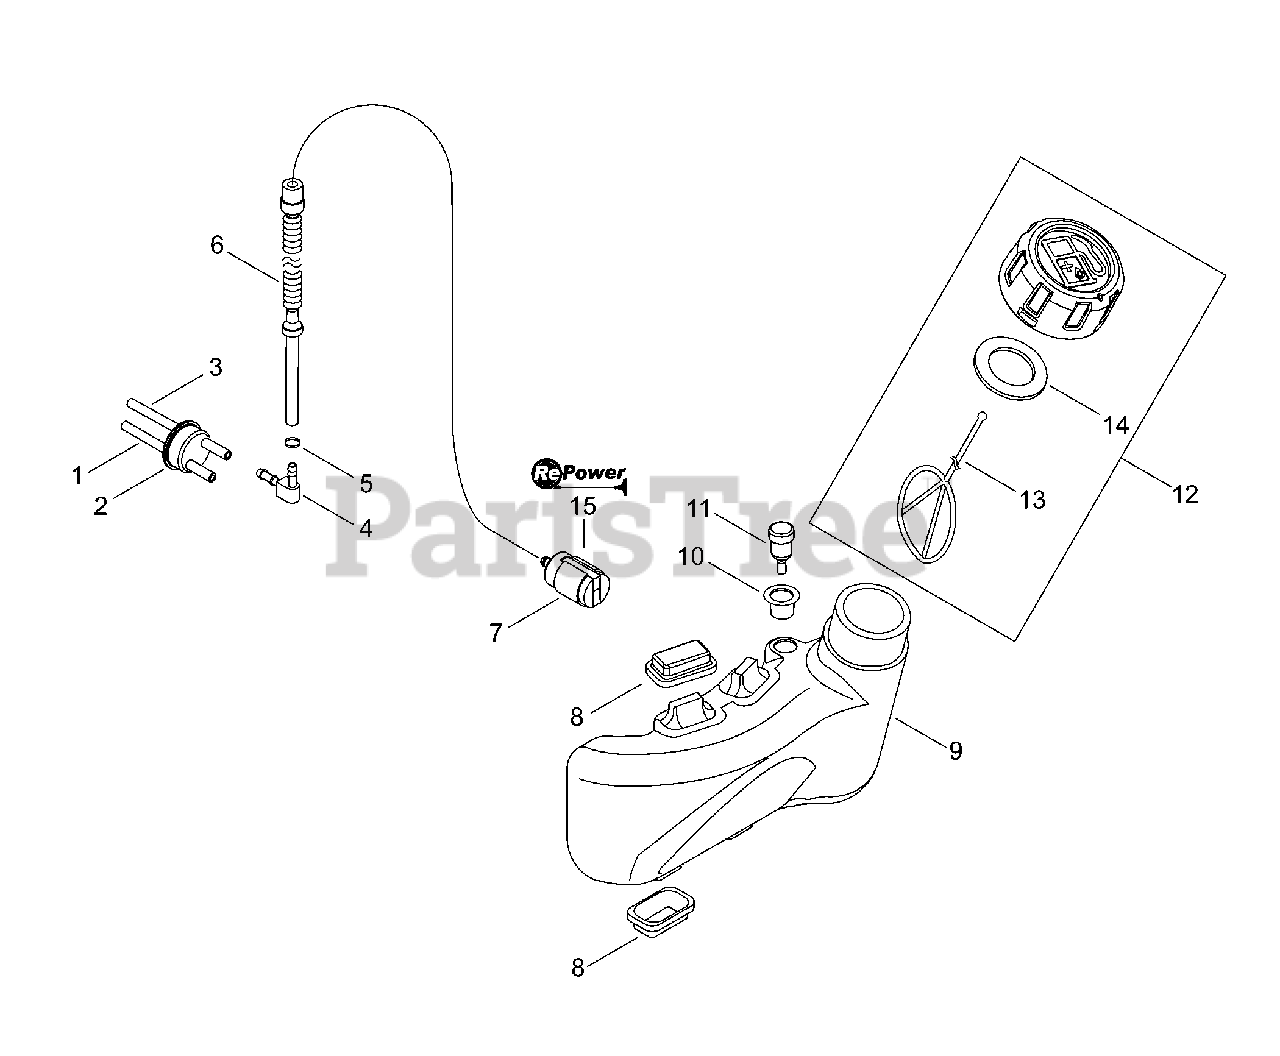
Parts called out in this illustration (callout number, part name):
1	PIPE 3×6×85
2	GROMMET
3	PIPE
4	JOINT,PIPE
6	PIPE
7	STRAINER, FUEL
8	CUSHION
9	TANK, FUEL
10	GROMMET,FUEL
11	VALVE,CHECK
12	FUEL CAP ASY
13	CONNECTOR,CAP
14	GASKET,FUEL CAP
15	FILTER KIT - REPOWER
15	TUNE-UP KIT - REPOWER
